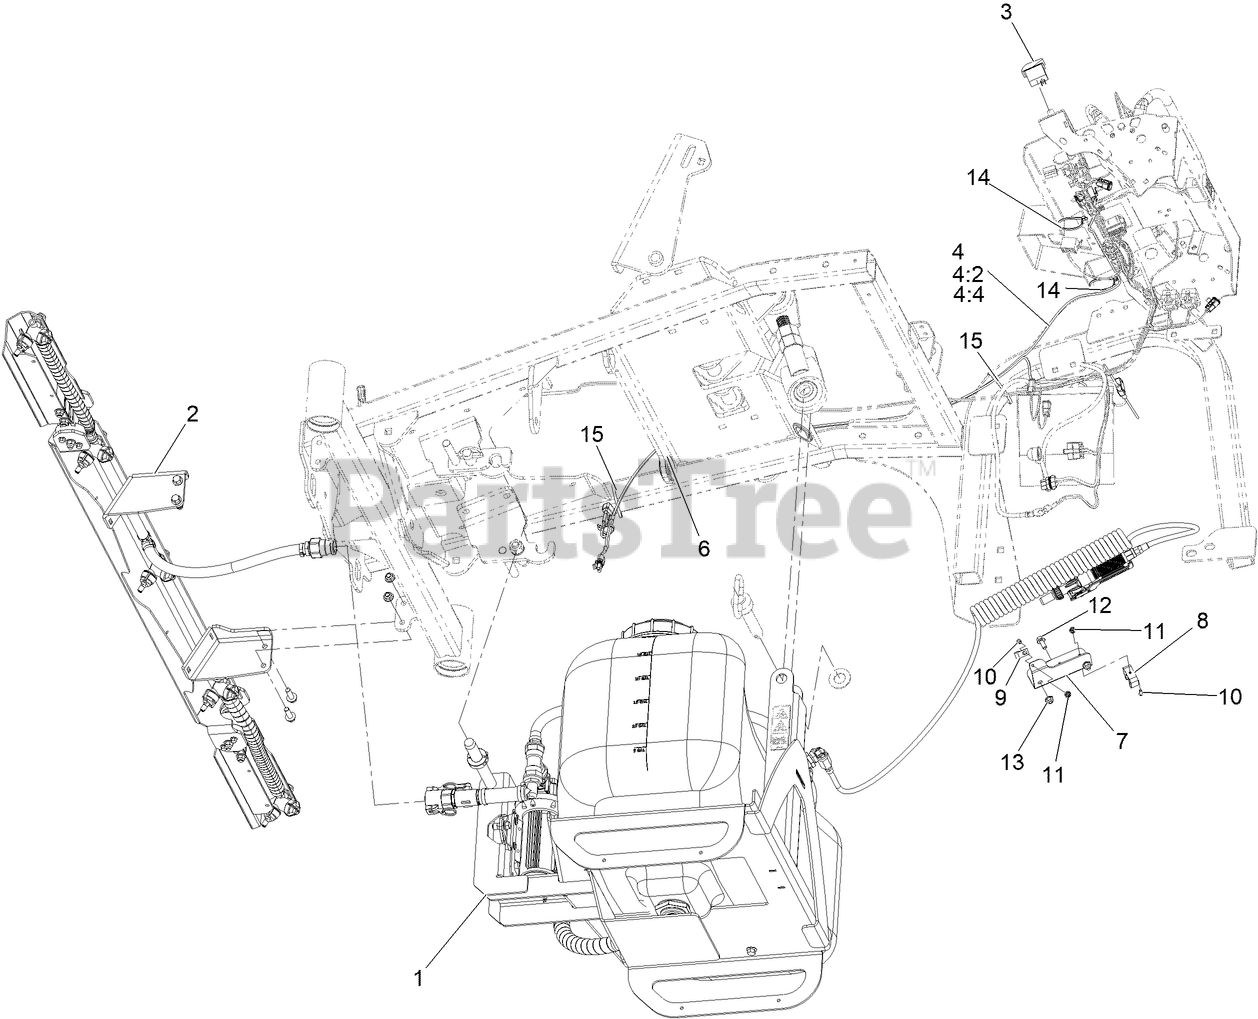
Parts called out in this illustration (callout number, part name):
1	Tank-ISO 30 Gal
2	BOOM-SPRAY 96 IN.
3	SWITCH-ROCKER
4	Harness-Accessory
4:2	FUSE-BLADE, 30 AMP
6	GROMMET
7	BRACKET-HOLDER, SPRAY WAND
8	Holder-Tool, Clip
9	CLAMP-R
10	Screw-HSBH
11	Nut-Hex Flange
12	SCREW-HHF
13	Nut-Hex Flange
14	TIE-CABLE
15	TIE-CABLE
